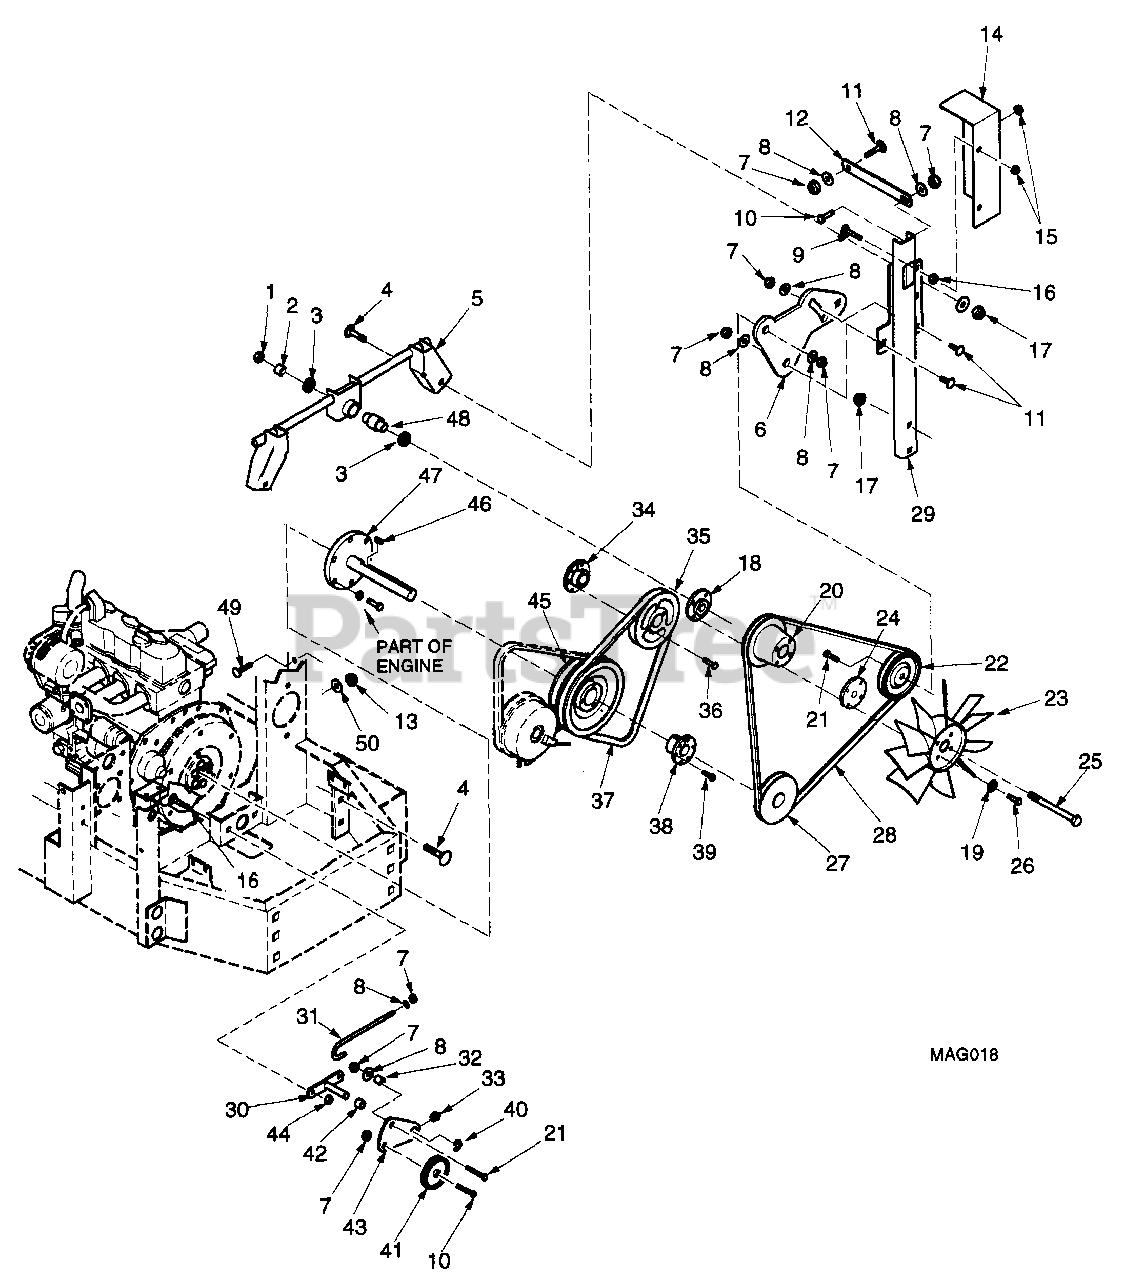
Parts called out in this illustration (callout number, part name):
1	HEX LOCKNUT, 1/2-20
2	SPACER, FAN
3	BEARING
4	CARRIAGE BOLT, 1/2-13 X 1-1/4
5	BRACKET, FAN MOUNTING(INCLUDES 3, 48)
6	IDLER BRACKET, FAN DRIVE
7	HEX LOCKNUT, ELASTIC STOP, 3/8-16
8	FLAT WASHER, 3/8(.391 X .938 X .105)
9	CARRIAGE BOLT, 1/4-20 X 1
10	BOLT, HEX HEAD, 3/8-16 X 1-1/4
11	CARRIAGE BOLT, 3/8-16 X 1-1/4
12	BRACE, FAN SUPPORT
13	SERR. FL. HEX NUT, 1/4-20
14	GUARD, PUMP BELT
15	HEX LOCKNUT, ELASTIC STOP, 1/4-20
16	CARRIAGE BOLT, 5/16-18 X 3/4
17	SERR. FL. HEX NUT, 1/2-13
18	HUB, FAN
19	LOCKWASHER, 1/4
20	PULLEY, FAN
21	BOLT, HEX HEAD, 3/8-18 X 1-3/4
22	PULLEY, BELT TENSIONING IDLER
23	FAN
24	HUB, FAN
25	BOLT, HEX HEAD, 1/2-20 X 4.75 LH THREAD
26	BOLT, HEX HEAD, 1/4-28 X 1
27	PULLEY, 4.25 O.D. X 1.4375 I.D.
28	BELT, FAN DRIVE
29	UPRIGHT, FAN SUPPORT - RH
30	BASE, IDLER PIVOT - PUMP
31	ROD, J-HOOK
32	SPACER, J PULL ROD
33	GREASE FITTING
34	TAPER HUB, .75 BORE
35	PULLEY, PUMP, 5.94 O.D.
36	BOLT, HEX HEAD, 1/4-20 X 3/8
37	BELT, PUMP DRIVE
38	TAPER HUB, 1-7/16 BORE
39	CPSCR, SOCKET HEAD, 1/4-20 X 1-1/4
40	RETAINING RING, .75 EXT
41	PULLEY, IDLER, 5.95 O.D.
42	BUSHING, OILITE - .75 I.D.
43	ARM, IDLER(INCLUDES 33, 42)
44	SERR. FL. HEX NUT, 5/16-18
45	PULLEY, DOUBLE GROOVE
46	KEY, 3/8 X 1-1/4
47	STUBSHAFT, CRANKSHAFT
48	SPACER
49	CARRIAGE BOLT, 1/4-20 X 1-1/4
50	FLATWASHER, 1/4
